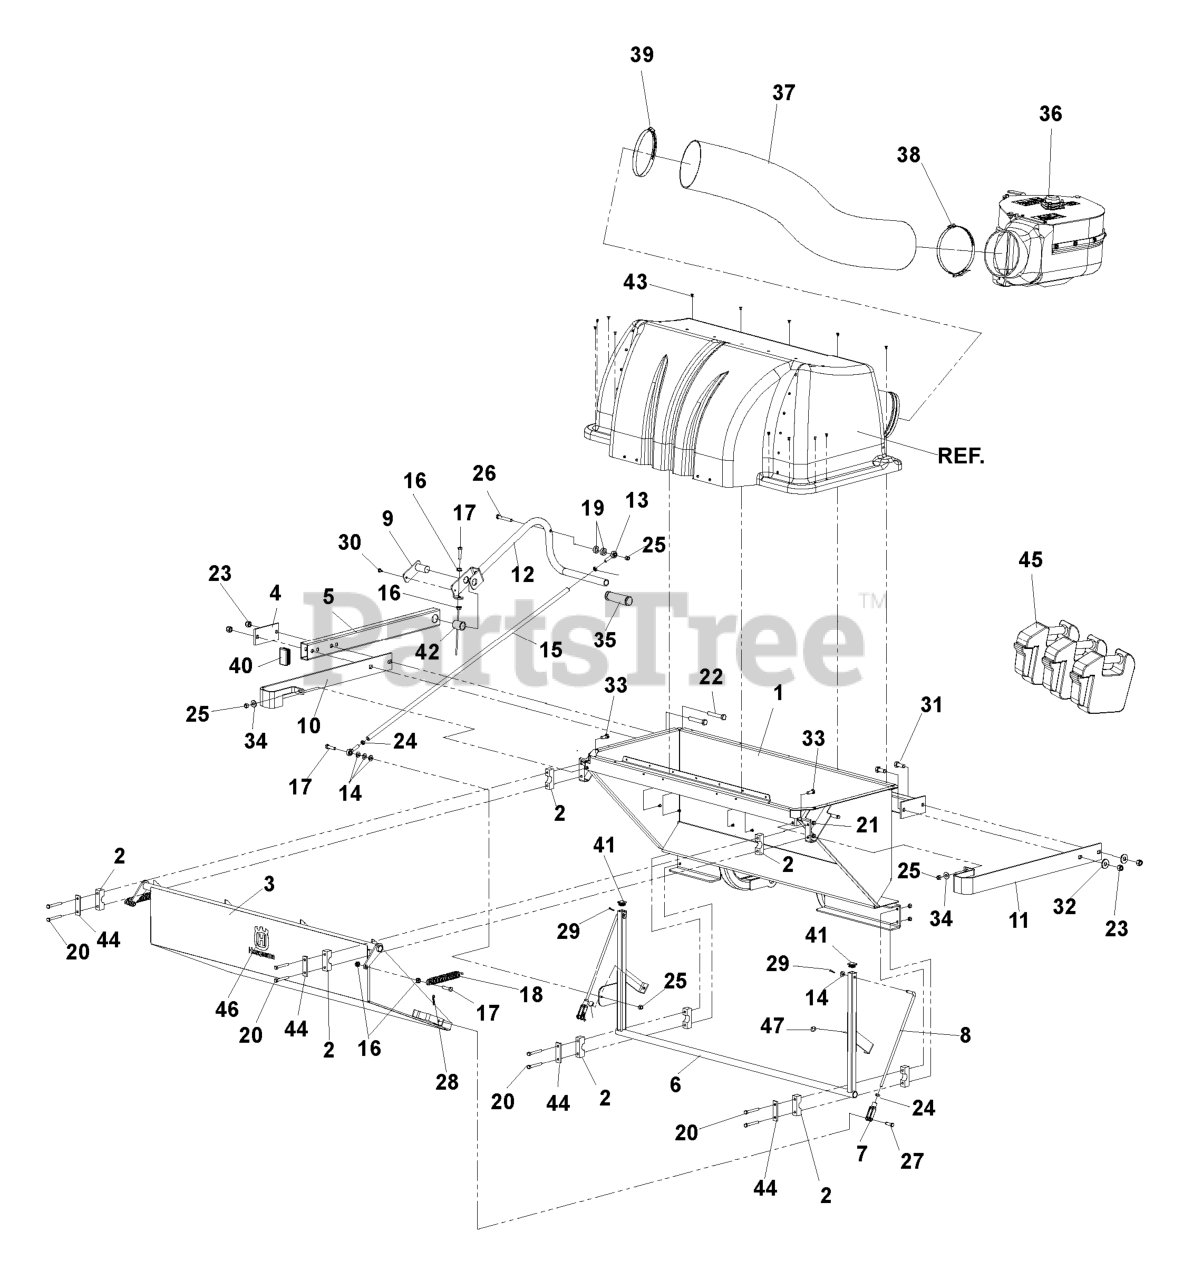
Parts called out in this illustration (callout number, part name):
1	WELDMENT - HOPPER
2	PILLOW BLOCK
3	WELDMENT - DOOR
4	PLATE - BACKING
5	TUBE - SUPPORT, HANDLE
6	WELDMENT - BELL CRANK
7	YOKE-3/8-24 PLTD
8	ROD.DOOR.COLECTION
9	WELDMENT - PIN, PIVOT
10	GUARD - L.H.
11	GUARD - R.H.
12	HANDLE WELDMENT
13	ROD END - 3/8-24 RH
14	WASHER 3/8 SAE FLAT
15	TUBE - THREADED
16	NUT 3/8C WHIZ
17	HCS 3/8C X 1 1/2
18	SPRING BAGGER
20	BOLT 5/16C X 2 1/2
21	NUT 5/16 NYLOC
22	SCREW, 1/2C X 3 HEX CAP
23	NUT 1/2-13 HEX NYLOC ZD
24	NUT 3/8-24 JAM
25	NUT 3/8-16 NYLOC
26	HEX SCREW 3/8-20 X 2.75
27	PIN CLEVIS, 3/8 X 1 1/4
28	HAIRPIN #2
29	RP_COTTER PIN 1/8 X 3/4
30	HWST 1/4C X 3/8
31	HCS 1/2-13 X 1-1/4
32	WASH USS FLAT 1/2
33	HCS 3/8-16X1.GRD.5.ZD
34	WASHER 3/8 FLAT
35	GRIP, HANDLE 1" ID BLACK
36	BLOWER ASSEMBLY
37	HOSE 7 X 58 CLEAR
38	OVER CTR BAND
39	HOSE CLAMP 4-1/8 TO 7"
40	PLUG - RETANGULAR TUBING
41	PLUG - SQUARE TUBE
42	BUSHING - BRONZE, 1.0"
43	RIVERT, 3/16, STAVEX
44	REINFORCEMENT BAR
45	FRT WEIGHT CAST PZ DFS
46	DECAL, CROWN H 5-1/4 SILVER
47	GROMMET, BUMPER
